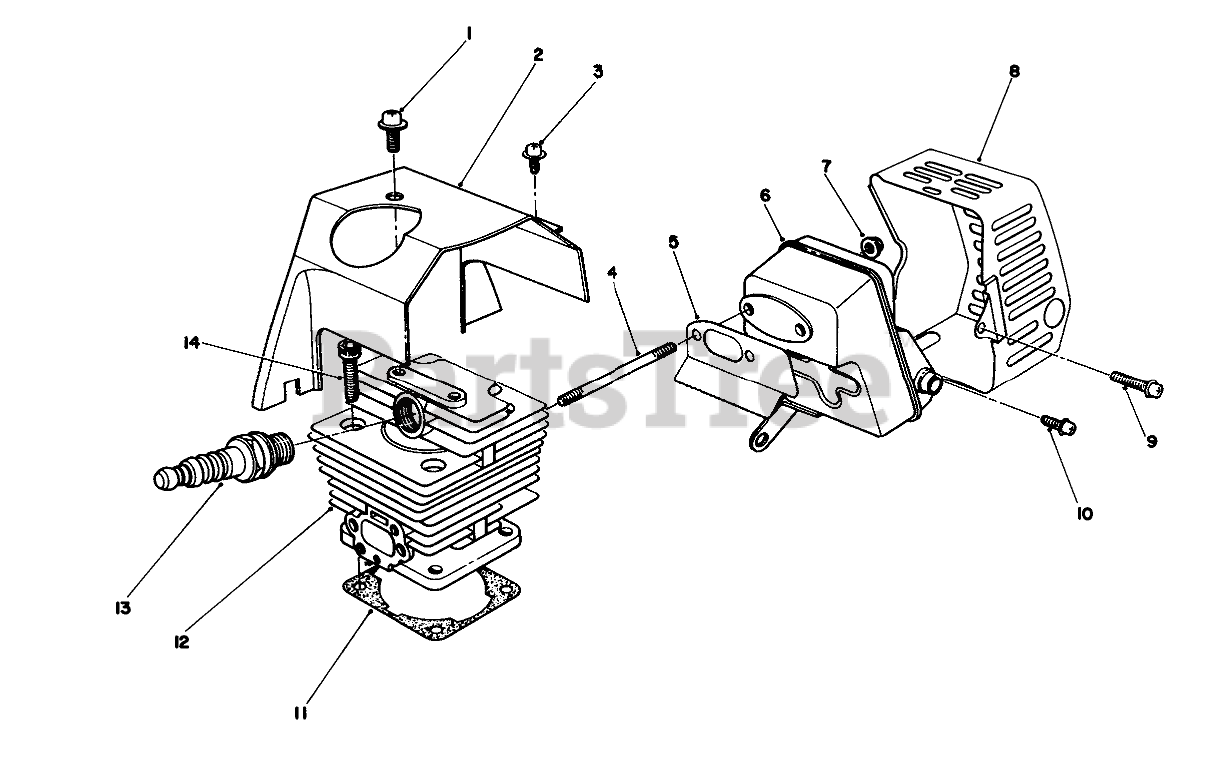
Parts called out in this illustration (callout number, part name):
1	Screw & Dishes
2	COVER,CYLINDER
3	Screw & Washer
4	BOLT,STUD
5	GASKET, MUFFLER
6	MUFFLER
7	NUT, FLANGE
8	COVER, MUFFLER
9	Screw & Washer
10	SCREW & WASHER
11	GASKET,CYLINDER
12	CYLINDER
13	SPARK PLUG (NGK)
